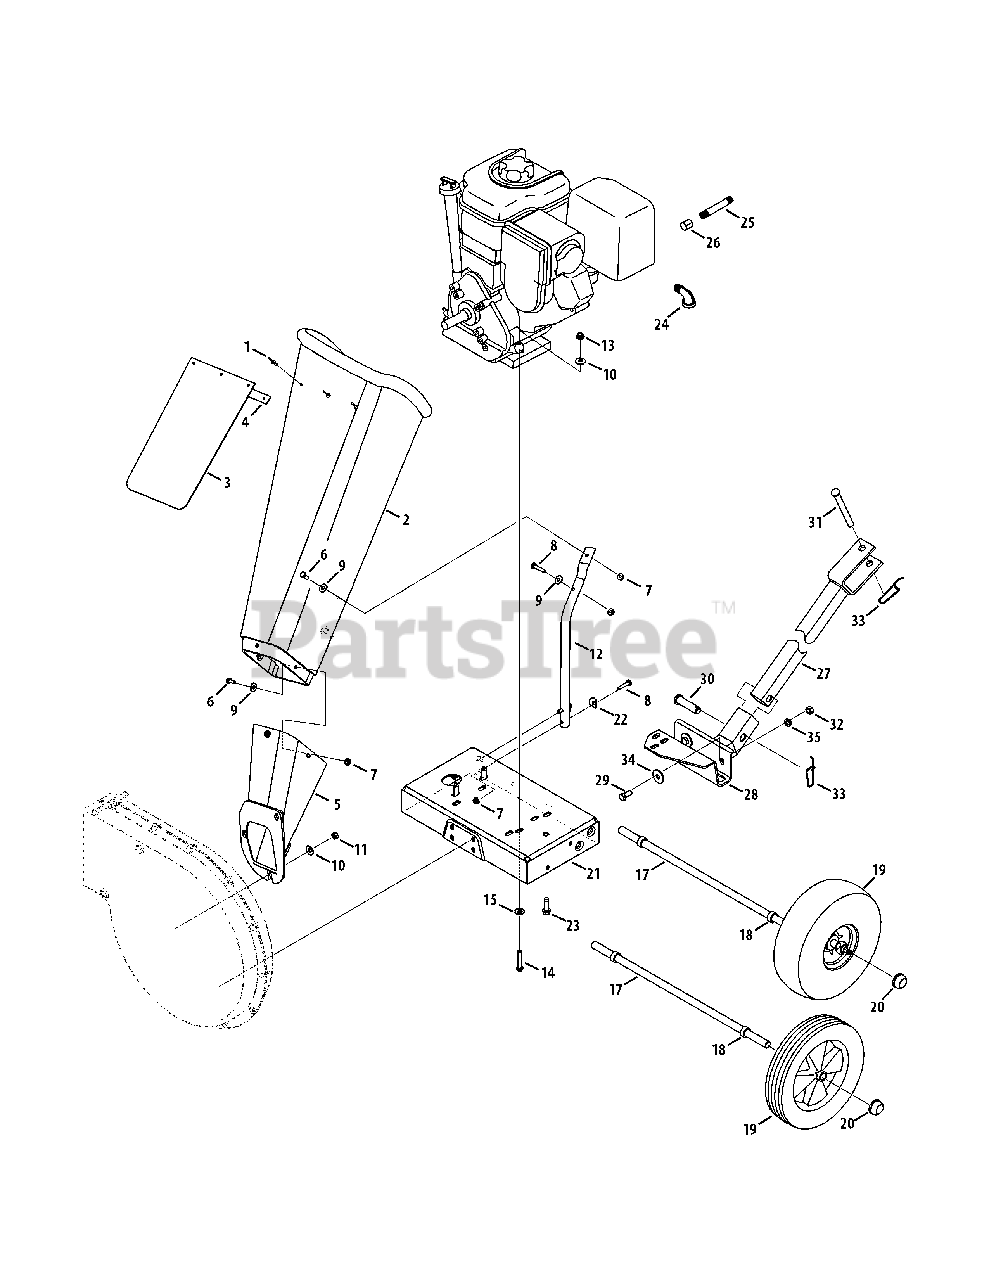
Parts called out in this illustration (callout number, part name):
1	Pop Rivet
2	Chipper Shredder Chute
3	Chute Flap
4	Chute Flap Strip
5	Chipper Chute Assembly
6	Hex Cap Screw 1/4 -20 x.620
7	Hex Lock Nut 1/4-20
8	Hex Cap Screw 1/4-20 x 1.25
9	Flat Washer.28 ID x.74 OD
10	Bell Washer.340 ID x.872 OD
11	Hex Nut 5/16-18
12	Support Brace
13	Hex Lock Nut 5/16-18
14	Hex Cap Screw 5/16-18 x 1.50
15	Bell Washer 5/16 x 1.0
17	Axle Assembly
18	Spacer
19	Wheel Comp., 10.0 x 2.5 Plastic
20	Push Cap
22	Washer,.320 ID x.93 OD
23	Screw, 3/8-16 x 1.250
24	Elbow Fitting
25	Oil Drain Pipe
26	Oil Drain End Cap
27	Tongue Hitch Mount
28	Base Hitch Mount
29	Hex Cap Screw, 3/8-16 x.88
30	Clevis Pin,.625 x 2.4
31	Clevis Pin,.50 x 4.62
32	Flange Lock Nut, 3/8-16
33	Spring Pin
34	Flat Washer,.411 x 1.25 x 1.0
35	Lock Washer, 3/8
